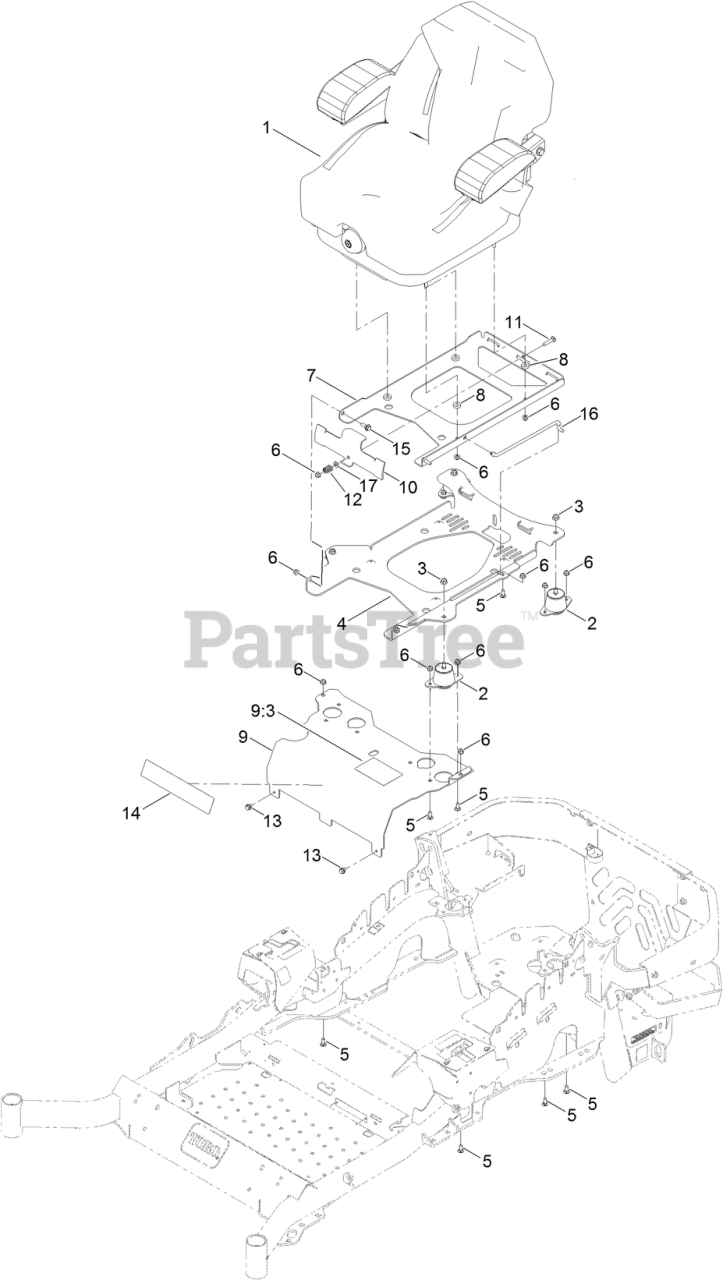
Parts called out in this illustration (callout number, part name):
1	SEAT-SUSPENSION
2	ISOLATOR-SEAT
3	NUT-HF, NI
4	PLATE-TILT, SEAT SUPPORT
5	SCREW-CARR
6	NUT-HF, NI
7	PLATE-FRAME, SEAT
9	SEAT MOUNT ASM
9:3	DECAL-SERVICE AID
10	PLATE-LATCH, SEAT
11	BOLT-CARR
12	SPRING-COMPRESSION
13	SCREW
14	DECAL
15	SCREW-SHOULDER
16	ROD-PROP
17	WASHER-PLAIN
